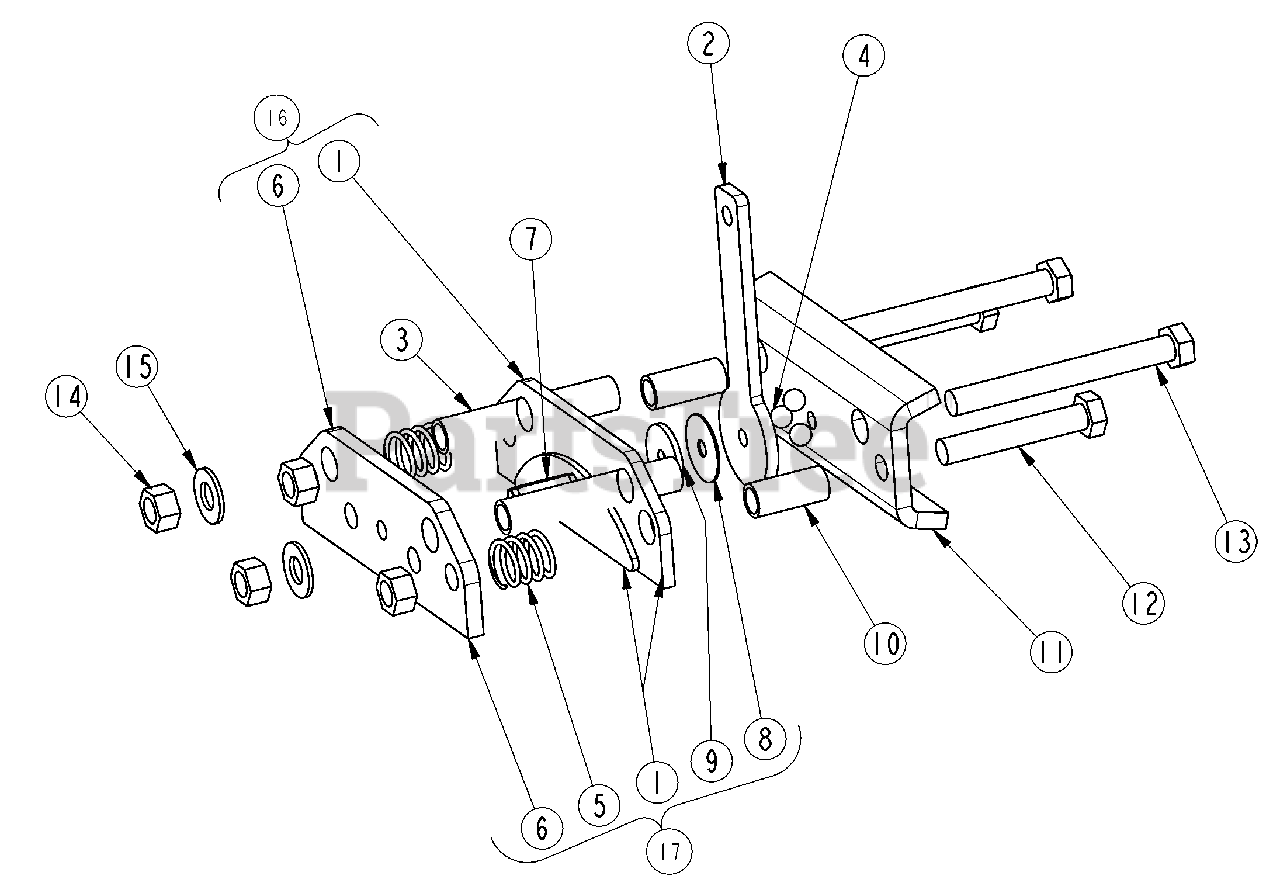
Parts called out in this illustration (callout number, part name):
1	STATOR ASSEMBLY
2	LEVER
3	SLEEVE
4	STEEL BALL
5	COMPRESSION SPRING
6	STATOR ASSEMBLY
7	SPRING PIN SLOTTED
8	SHIM
9	THRUST WASHER
10	SLEEVE
11	STATIONARY ACTUATOR
12	BOLT, HEX 3/8-16 X 2 1/4 GR5
13	HHCS 3/8-16X3 1/2 GR8 PLT
14	NUT HEX TOP LOCK 3/8-16 PLT
15	WASHER FLAT 3/8 SAE PLT
16	BRAKE PAD REPLACEMENT KIT
17	CALIPER REPAIR KIT
